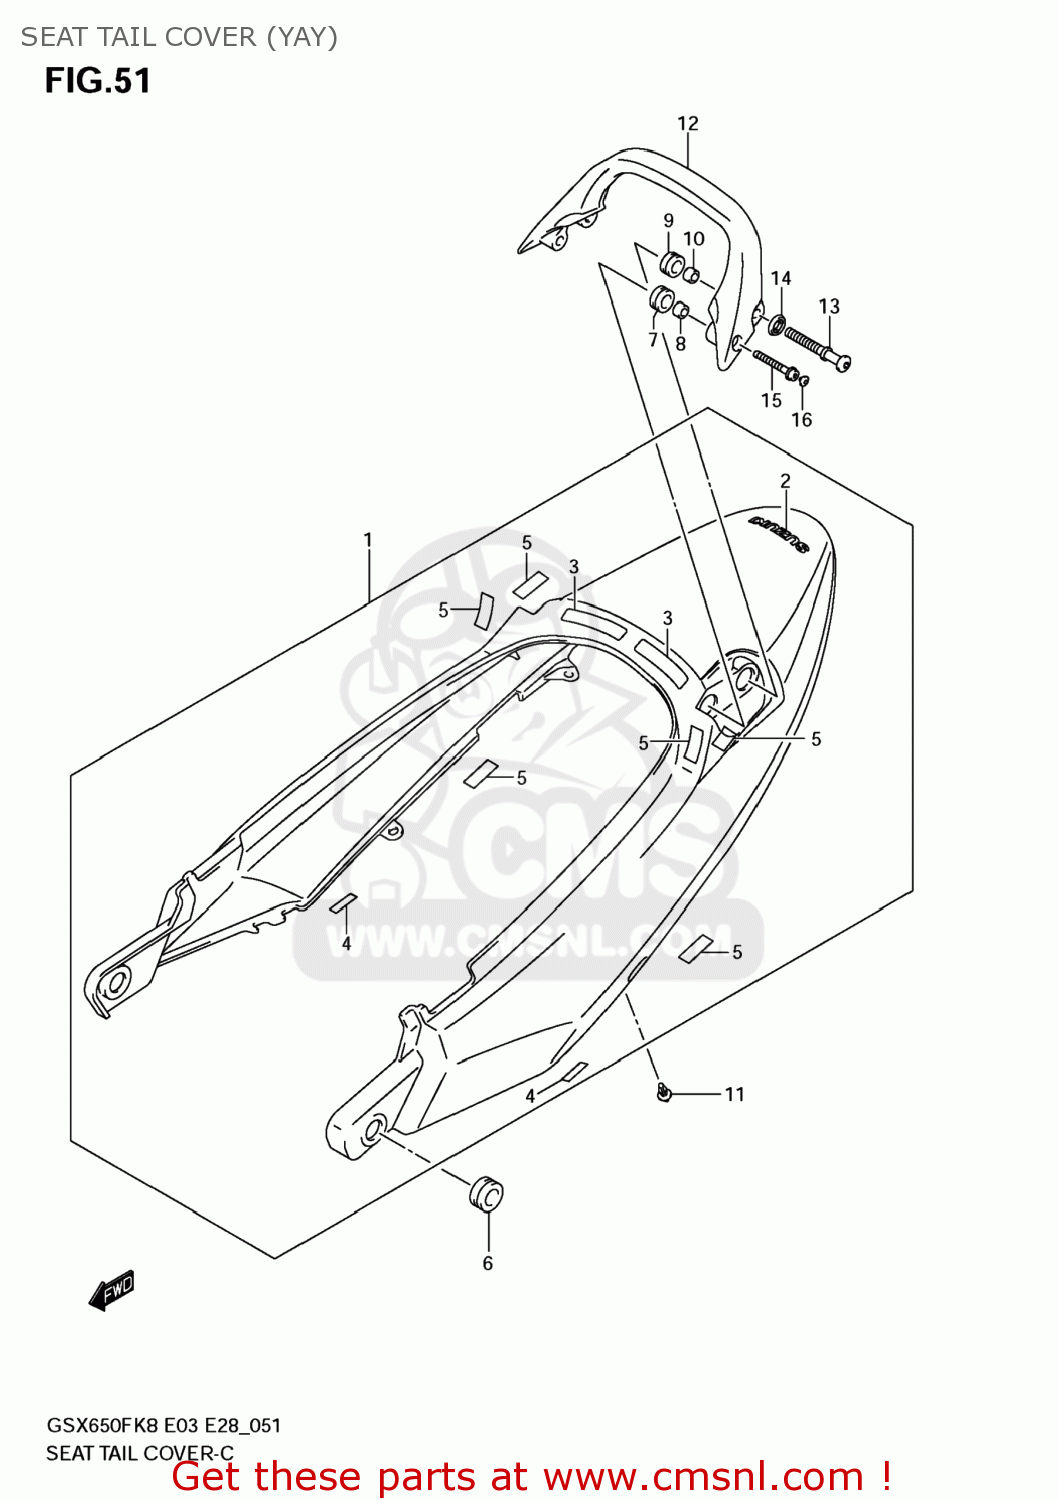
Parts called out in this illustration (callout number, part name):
1	COVER ASSY,SEAT TAIL(BLACK)
2	EMBLEM,SUZUKI
3	TAPE,COVER
4	TAPE,SEAT TAIL COVER
5	PROTECTOR,FRAME COVER
6	CUSHION
7	CUSHION
8	SPACER(6.5X12X9)
9	CUSHION
10	SPACER,8.5X14X9
11	CLIP(BLACK)
12	HANDLE,PILLION
13	HOOK,PILLION RIDER HANDLE
14	WASHER,HOOK
15	BOLT
16	CAP(OD:10)
